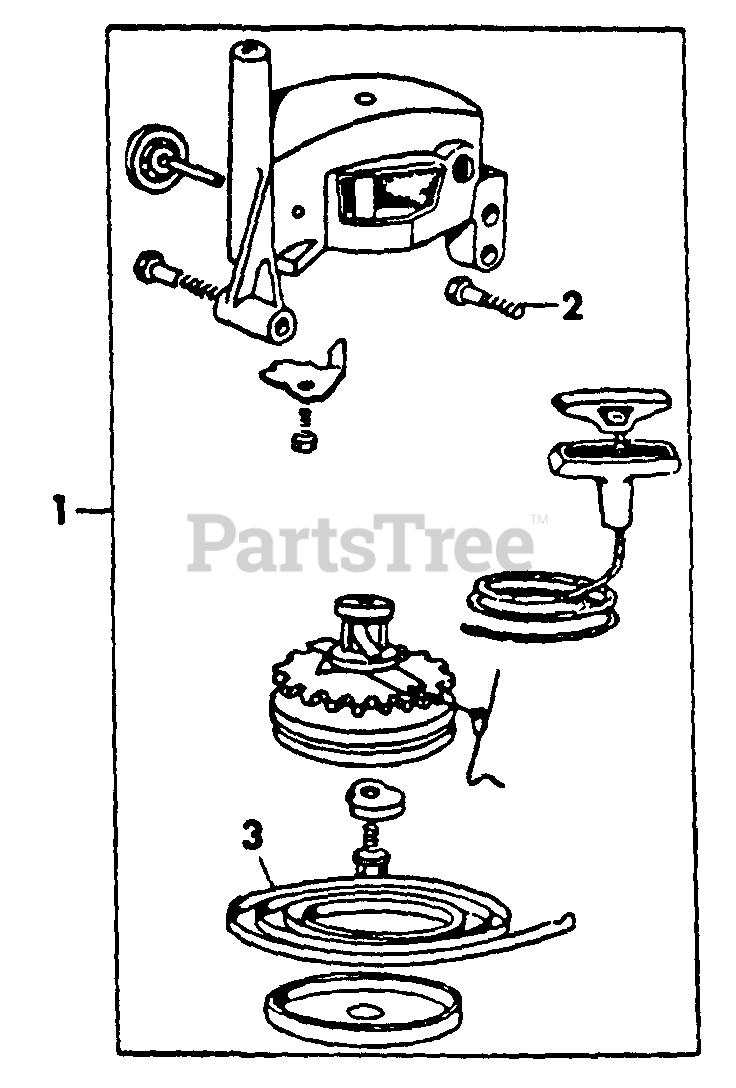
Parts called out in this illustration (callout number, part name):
1	STARTER, VERTICAL PU
2	SCREW, VERTICAL PULL STARTER
3	SPRING, VERTICAL PULL SPRING
